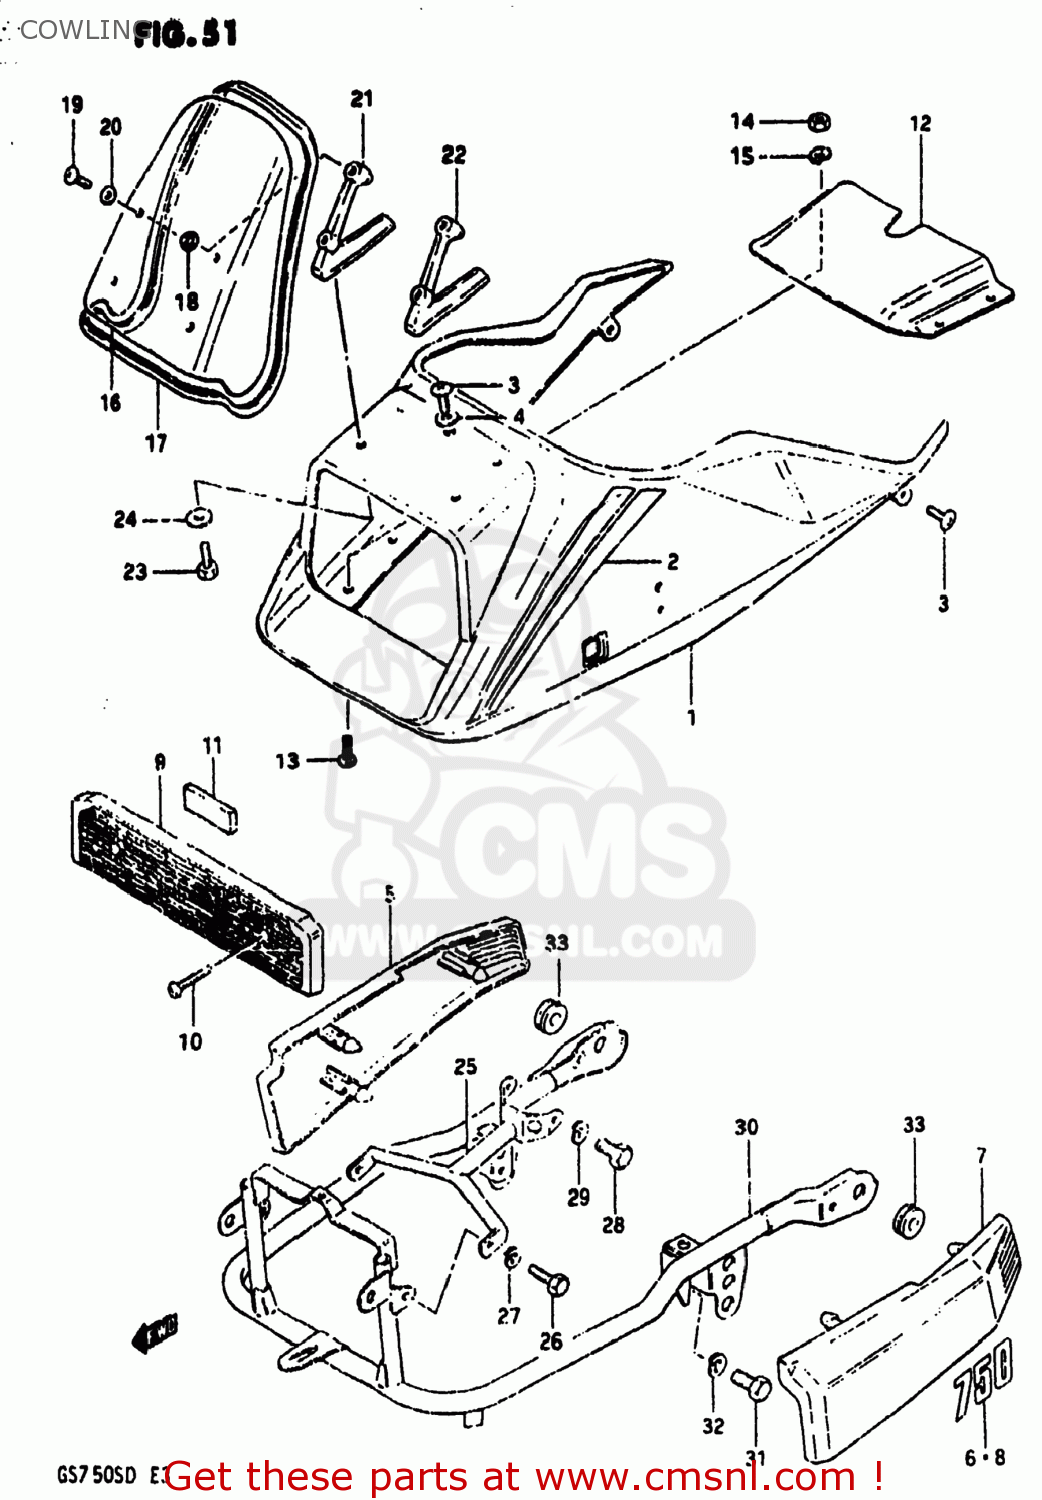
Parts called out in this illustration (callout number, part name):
1	COWLING ASSEMBLY
2	TAPE SET,COWLING
3	SCREW 6X12
4	WASHER
5	COVER,COWLING,RIGHT
6	EMBLEM,FRAME COVER
7	COVER,COWLING,LEFT
8	EMBLEM,FRAME COVER
9	COVER,COWLING LOWER
10	SCREW
11	CUSHION
12	COVER,COWLING LOWER FR
13	SCREW 6X12
14	NUT
15	LOCK WASHER
16	WINDOW,COWLING
17	MOLD,COWLING
18	CUSHION
19	SCREW
20	WASHER(5.2X11X1)
21	BRACE,COWLING WINDOW RH
22	BRACE,COWLING WINDOW LH
23	BOLT
24	WASHER(6.5X16X1.2)
25	BRACKET,COWLING UPPER
26	BOLT, UPPER
27	LOCK WASHER
28	BOLT
29	LOCK WASHER
30	BRACE,COWLING RR
31	BOLT 8X12
32	LOCK WASHER
33	CUSHION
